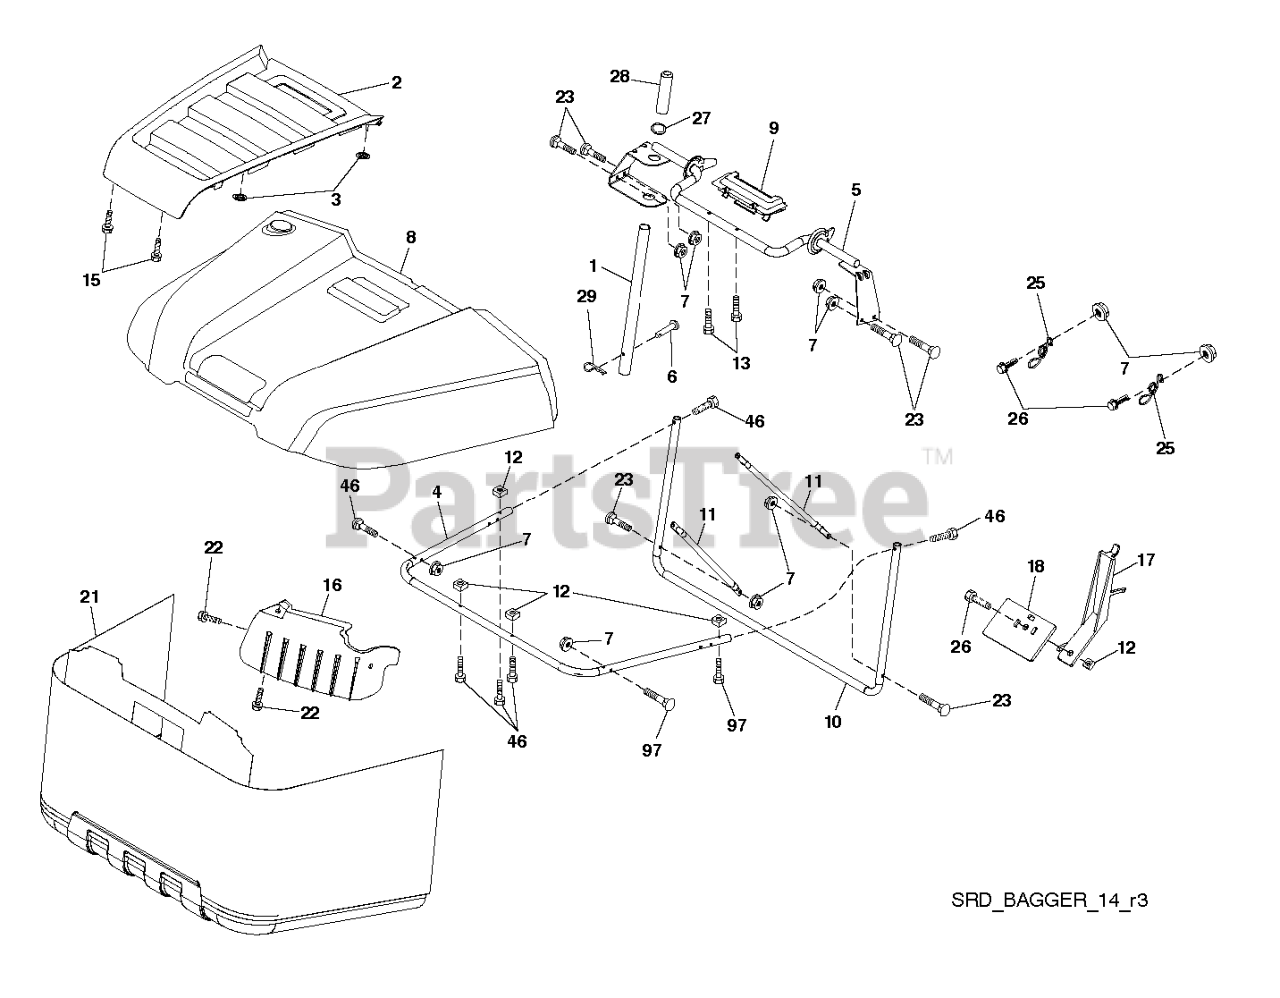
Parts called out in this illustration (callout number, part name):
1	TUBE.HANDLE.BAGGER.CRD/SRD.BLA
2	APPLIQUE.TOP.BAG.SRD.ORANGE
3	NUT.PUSH.156
4	SUBASM.TOP.BAGGER.TUBE
5	FRAME.ASM.TOP.BAGGER.SRD
6	RIVET,DRILLED
7	NUT T
8	BAGGER.TOP.SRD.APPLIQUE
9	INSERT.HANDLE.BAGGER.(2 2)
10	FRAME.FRONT.SRD.BAGGER
11	TUBING.BRACE.BAGGER.SRD.BLACK
12	NUT.SQUARE.1/4
13	SCREW.1/4X1.150.HXWSH
15	SCREW,#8.FLAT.HEAD.DRILL.TIP
16	DEFLECTOR.BAGGER.SRD
17	LEVER.BAGGER.FULL.SRD.BLACK
18	PADDLE.BAGGER.FULL.SRD.BLACK
21	BAG.ASM.BAGGER.SRD.HUSQVA.GREY
25	SPRING.LATCH.BAGGER.SRD
26	SCREW HEX CRT
27	RB GROMMET.RUBBER.SRD
28	GRIP.HANDLE.BLACK
29	PIN.COTTER.5/16.BOW TI
46	SCREW.HEXCAP.1/4X-20X1.500
97	SCREW.TORX.BUTN.HD.1/4-20-1.5"
